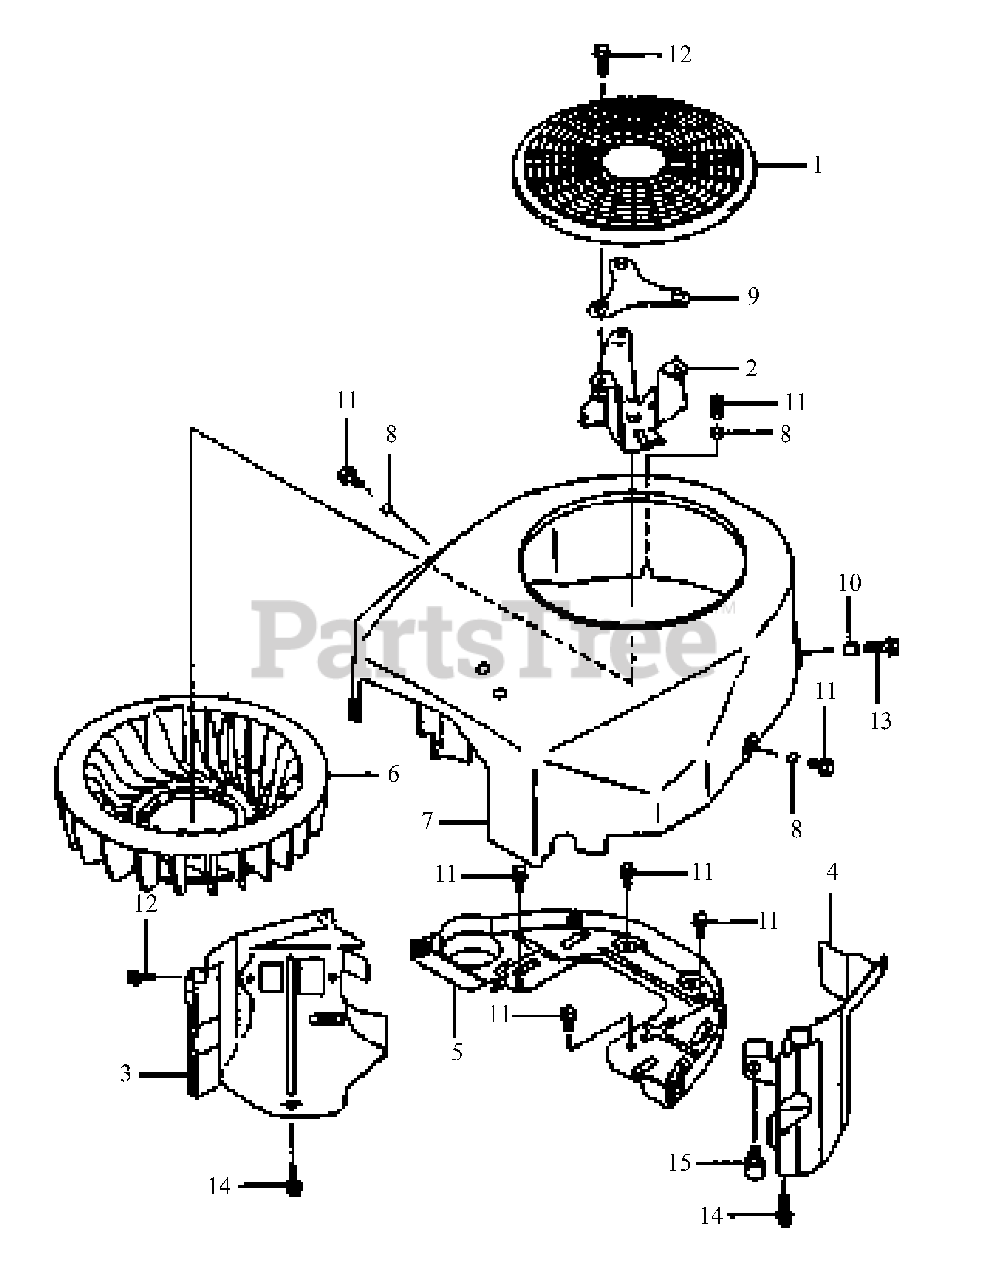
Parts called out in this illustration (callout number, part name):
2	Bracket, Complete
3	Shroud, Engine
4	Shroud, Engine
5	Shroud, Engine
6	Fan
8	Spacer, 6.2 x 7.9 x 5
10	Spacer 6.5 x 7.9 x 10.5
11	Bolt, Flange
12	Bolt, Flange
13	Bolt, Flange
14	Bolt, Flange
15	Bolt, Flange
